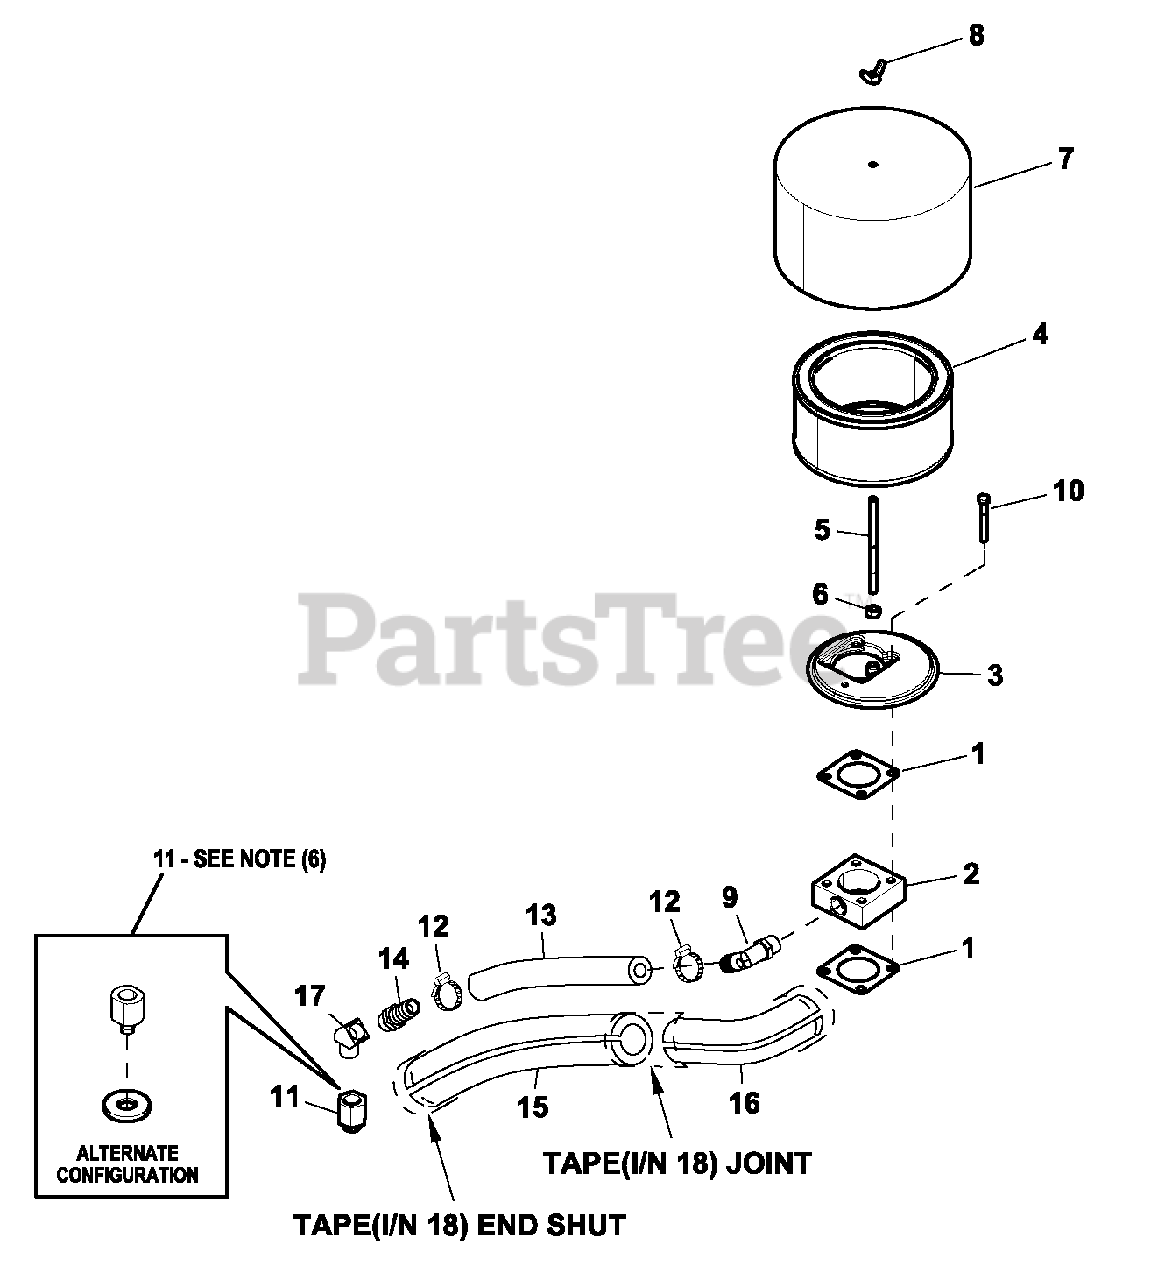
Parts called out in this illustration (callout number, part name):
1	GASKET BOSCH 32 & 40
2	ADAPTOR PCV INTAKE
3	ADAPTOR - CARBURETOR
4	ELEMENT, AIR CLEANER
5	STUDTH 1/4-20X4-1/2 G2ZNC
6	NUT HEX 1/4-20 STEEL
7	PLATE, AIR CLEANER TOP 2.4L
8	NUT WING 1/4-20 W/NY INS ST ZN
9	BARBED EL90D 1/2NPTX3/4
10	SCREW HHC M5-0.8 X 40 G8.8
11	FITTING VENT VALVE COVER
12	CLAMP HOSE #8 .53-1.00
13	HOSE 3/4 ID SAE-30R2 (17.5"LG)
14	BARBED STR 1/2NPTX3/4
15	PIPE INSULATION (17"LG)
16	PIPE INSULATION ELBO
17	ELBOW 45D STREET 1/2NPT BRASS
18	PIPE INSULATION TAPE (14"LG)
